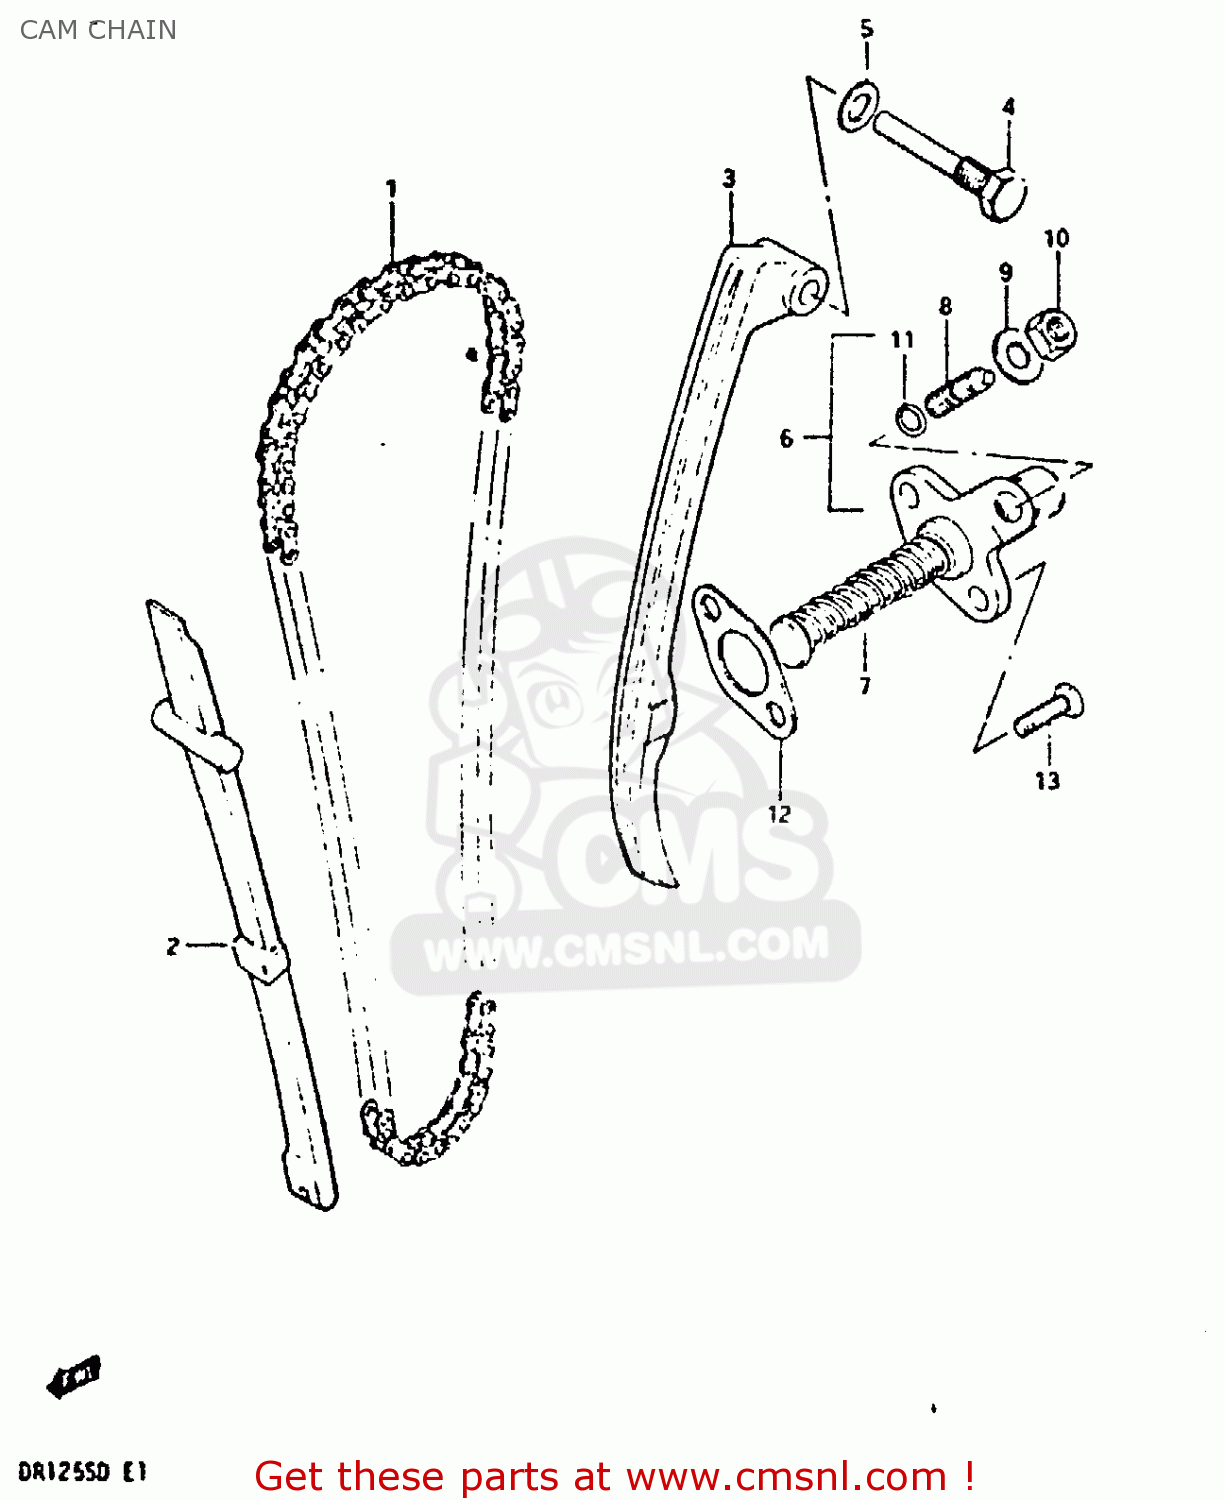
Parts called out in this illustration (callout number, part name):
1	CHAIN,CAMSHAFT DRIVE
2	GUIDE,CAM CHAIN
3	TENSIONER,CAM CHAIN
4	BOLT,CAM CHAIN TENSIONER
5	GASKET 8.2X14X1 (NAS)
6	ADJUSTER ASSEMBLY,TENSIONER
7	SPRING
8	SCREW
9	WASHER,8.5X16X
10	NUT
11	O-RING
12	GASKET,TENSIONER ADJUSTER (NAS)
13	BOLT
